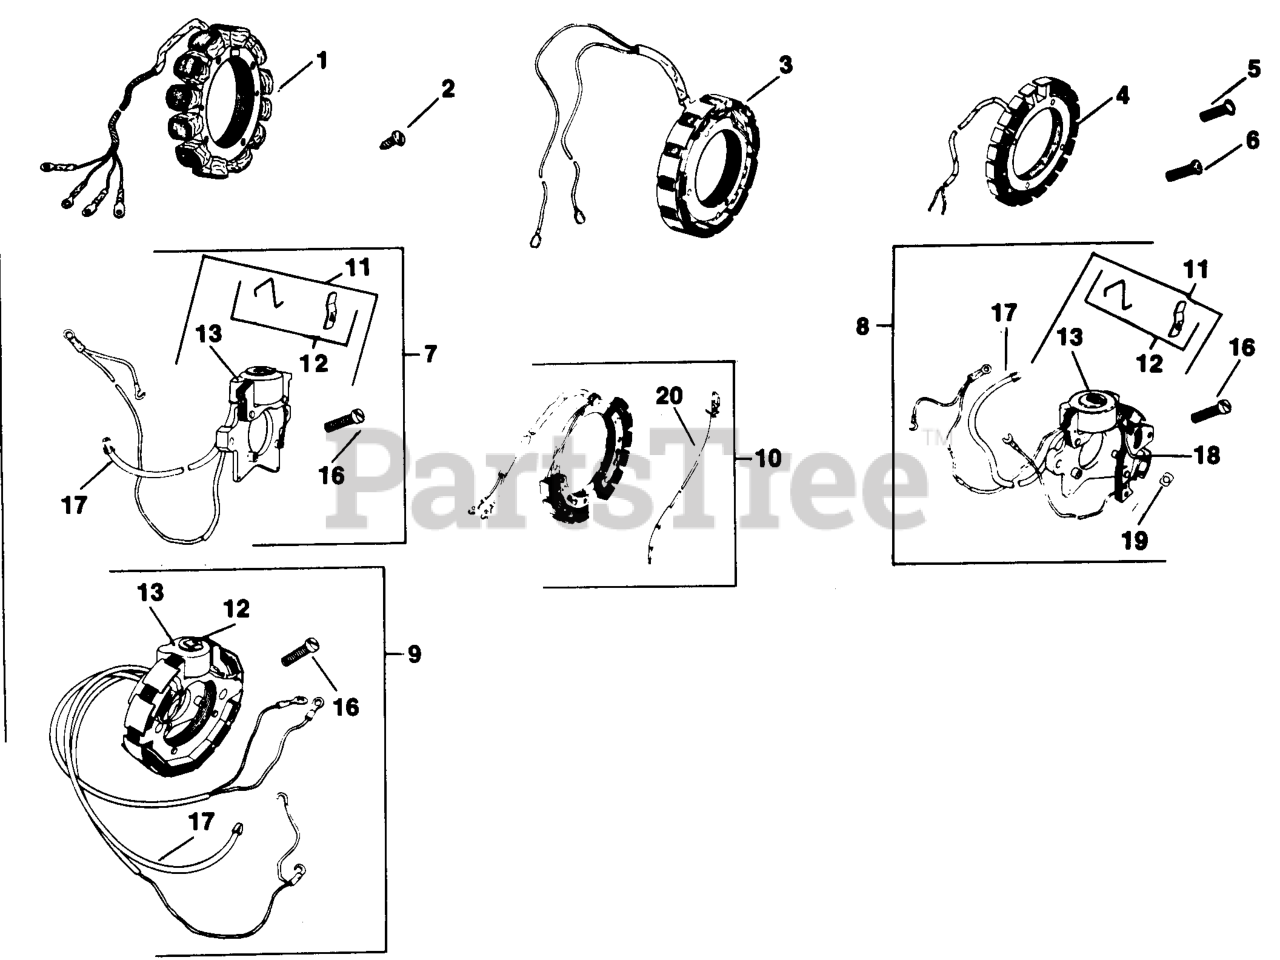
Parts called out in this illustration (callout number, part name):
5	SCREW - DISCONTINUED
7	STATOR - DISCONTINUED
11	KIT, COIL
12	KIT, CLIP - DISCONTINUED
17	LEAD - DISCONTINUED
